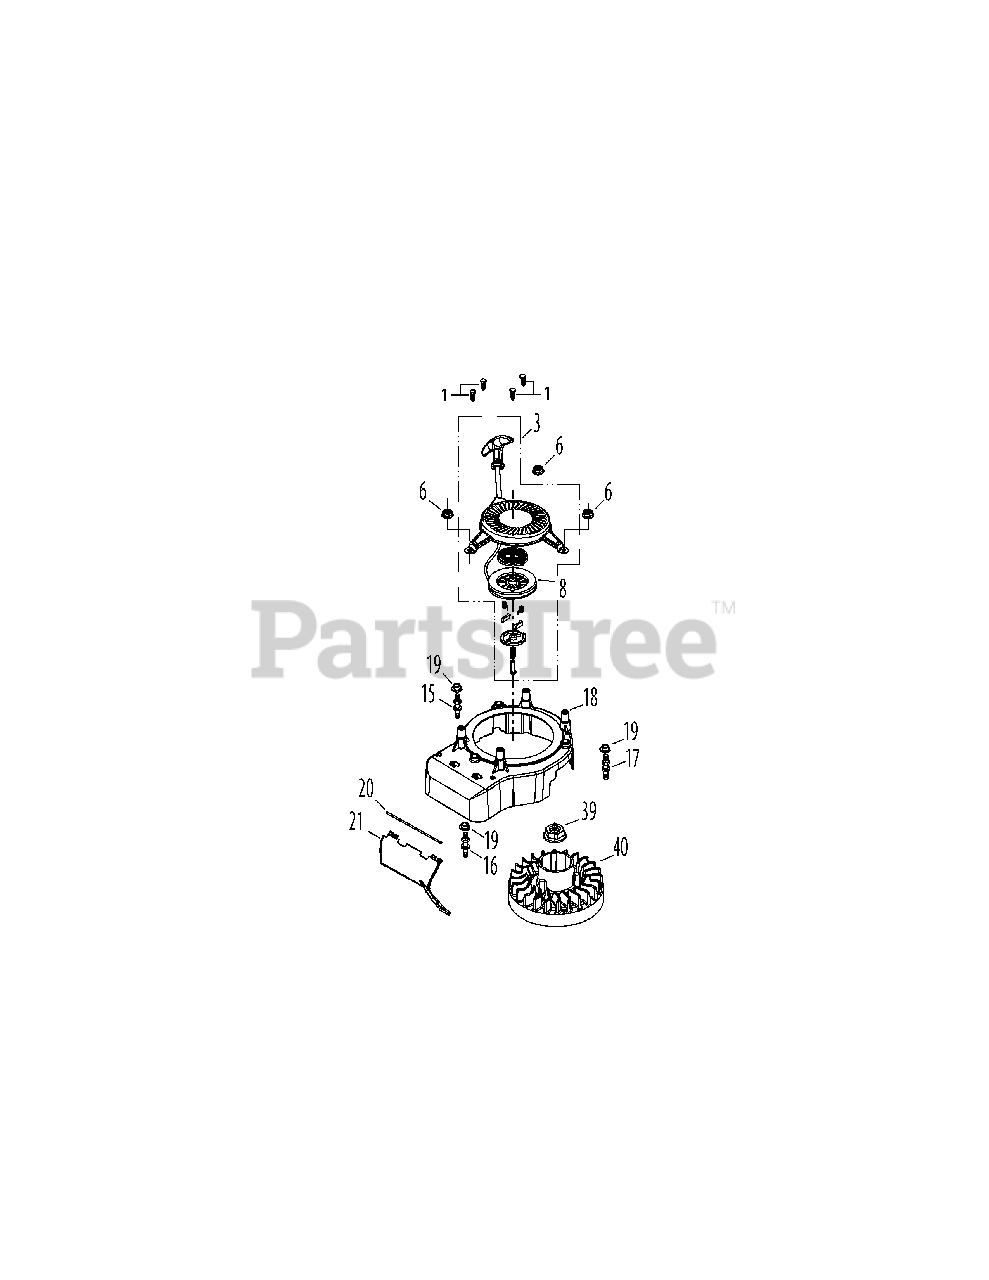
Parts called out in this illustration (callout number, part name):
1	Self-Tapping Bolt, #12-16 x 1.0"
3	Recoil Starter Assembly
6	Nut M6 X 10 Mm
8	Recoil Spring & Pulley Assembly
15	Starter/Shroud Stud M6x85-48
16	Starter/Shroud Stud M6x87-51.5
17	Starter/Shroud Stud M6x79
18	Inner Shroud
19	Engine Shroud Spacer
20	Air Vane Shaft
21	Air Vane
39	Flywheel Nut M14
40	Flywheel
